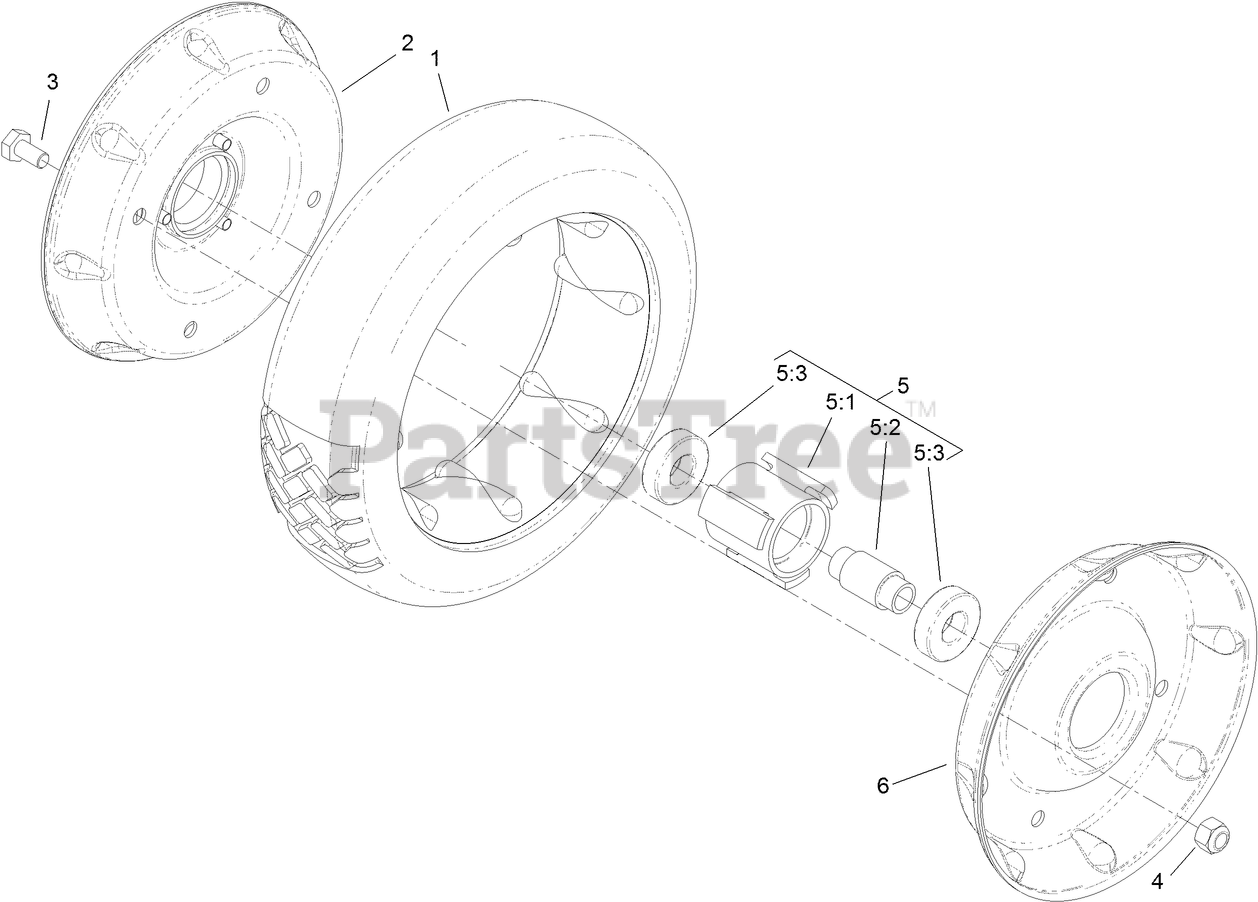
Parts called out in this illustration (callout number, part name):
2	WHEEL HALF AND GEAR ASM
3	SCREW-HH
4	NUT-LOCK, NI
5	HUB AND BEARING ASM
5:1	HUB-BEARING
5:2	SPACER-BEARING
5:3	BEARING-BALL
6	RIM-HALF, WHEEL
